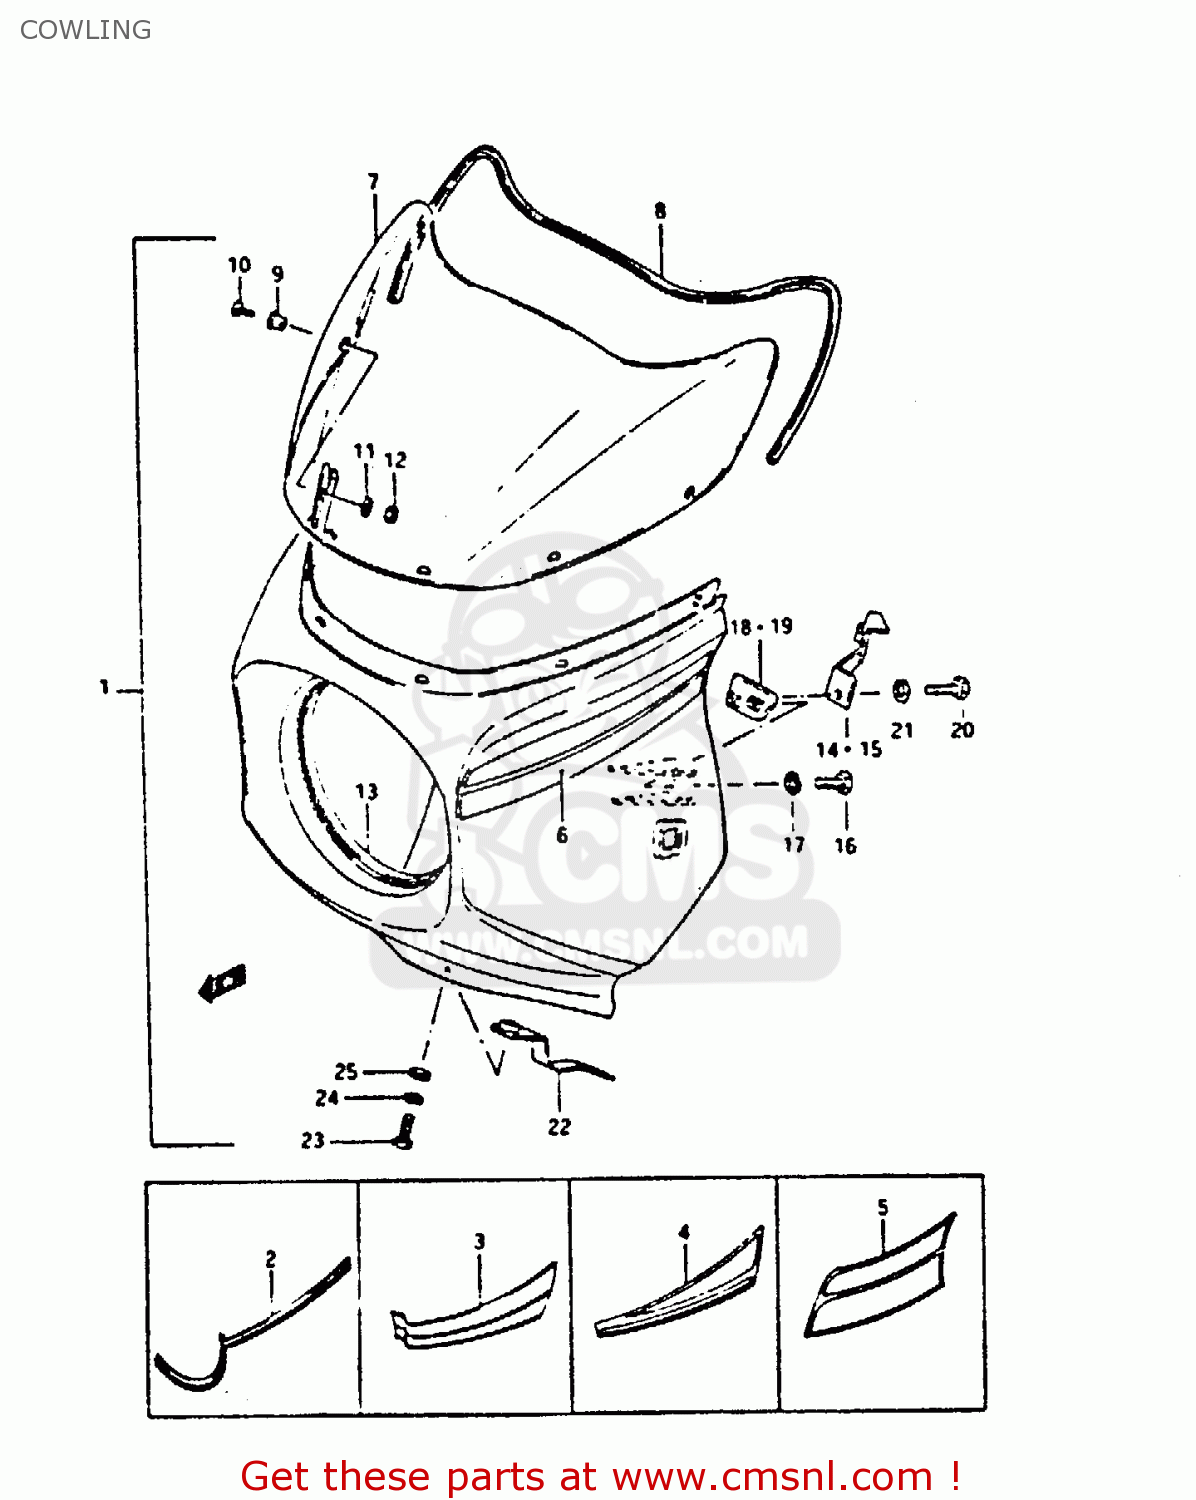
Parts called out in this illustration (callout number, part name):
1	COWLING ASSY (WHITE/RED)
2	TAPE SET
3	TAPE SET
4	TAPE SET
5	TAPE SET
6	TAPE SET
7	WINDOW
8	MOLD,COWLING
9	CUSHION
10	SCREW
11	WASHER,5MM
12	NUT 8MM
13	MOLDING,HEADLAMP GRILL
14	BRACKET,COWLING RH
15	BRACKET,COWLING LH
16	BOLT
17	WASHER,LOCK
18	BRACKET, FITTING RH
19	BRACKET, FITTING LH
20	BOLT 6X16
21	WASHER (6.5X18X1.6)
22	BRACKET, LOWER
23	BOLT
24	WASHER,LOCK
25	WASHER
